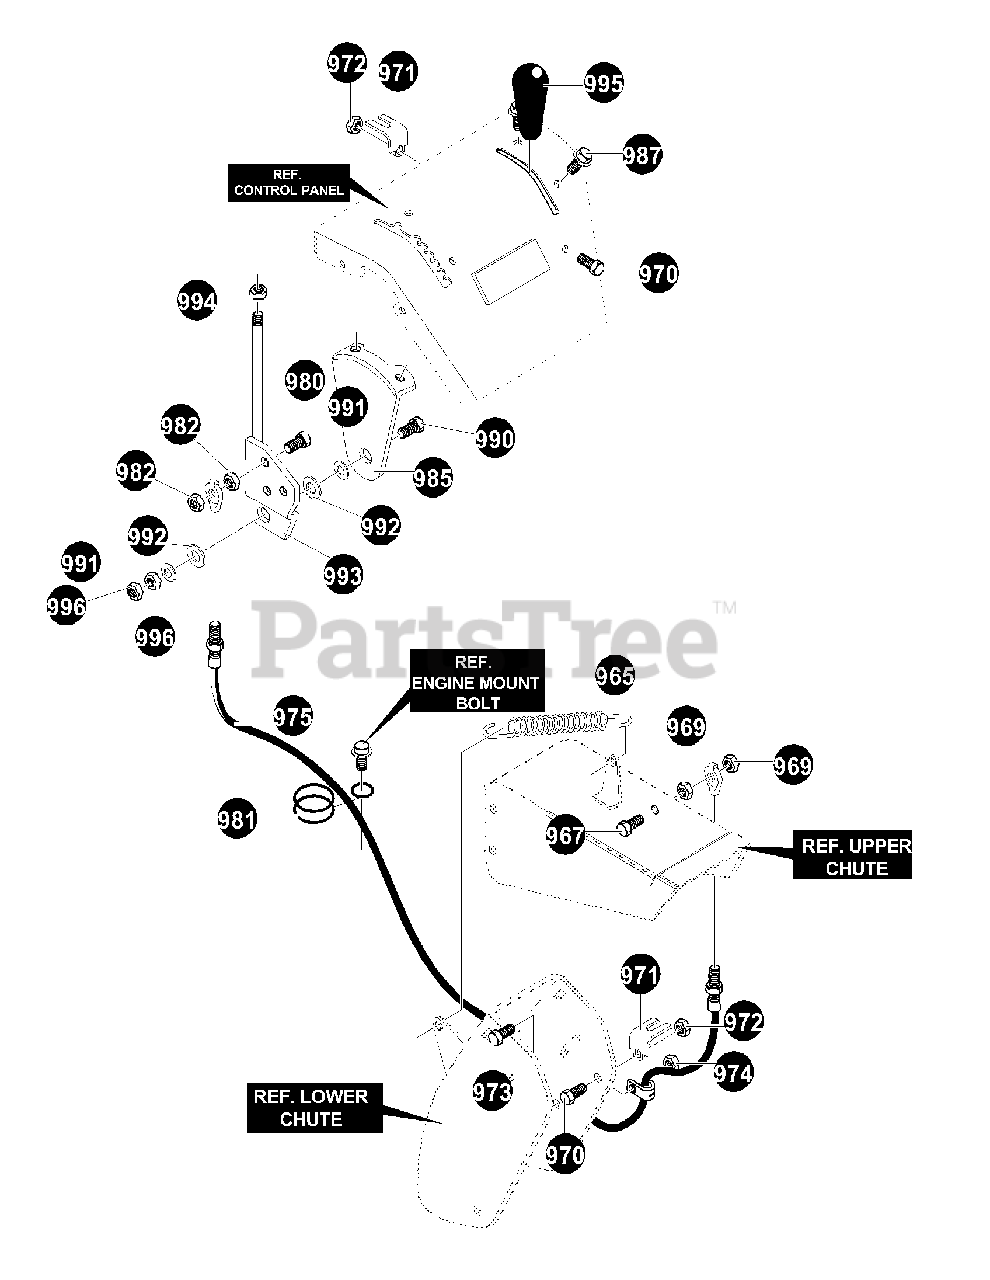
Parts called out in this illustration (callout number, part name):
965	SPRING, TENSION
967	SCREW 1/4-20X1.00
969	NUT, 1/4-20 REGHEXCTRLK
970	SCREW 5/16-18X.50
971	BRACKET, CABLE CHUTE
972	NUT, 5/16-18 REGHEXCTRLK
973	SCREW, 10-24X.38 SLHWATAP
974	NUT, #10-24 HEXNYLLK
975	CABLE, CHUTE CONTROL
980	SCREW 1/4-20X1.00
981	WIRE, FORM REMOTE CABLE
982	NUT, 1/4-20 REGHEXCTRLK
985	BRACKET, SPEED CONTROL
987	SCREW, 5/16-18X.T0 WAHHTAP
990	SCREW, 3/8-16X1.75
991	FLATWASHER, .406X.81X.065
992	WASHER, SPRING .392X1.05X.082
993	HANDLE, ASSY SPD CONTROL
994	NUT, 3/8-16 REGHEXCTRLK
995	HANDLE, 3/8-16
996	NUT, 3/8-16 HEXNYL
